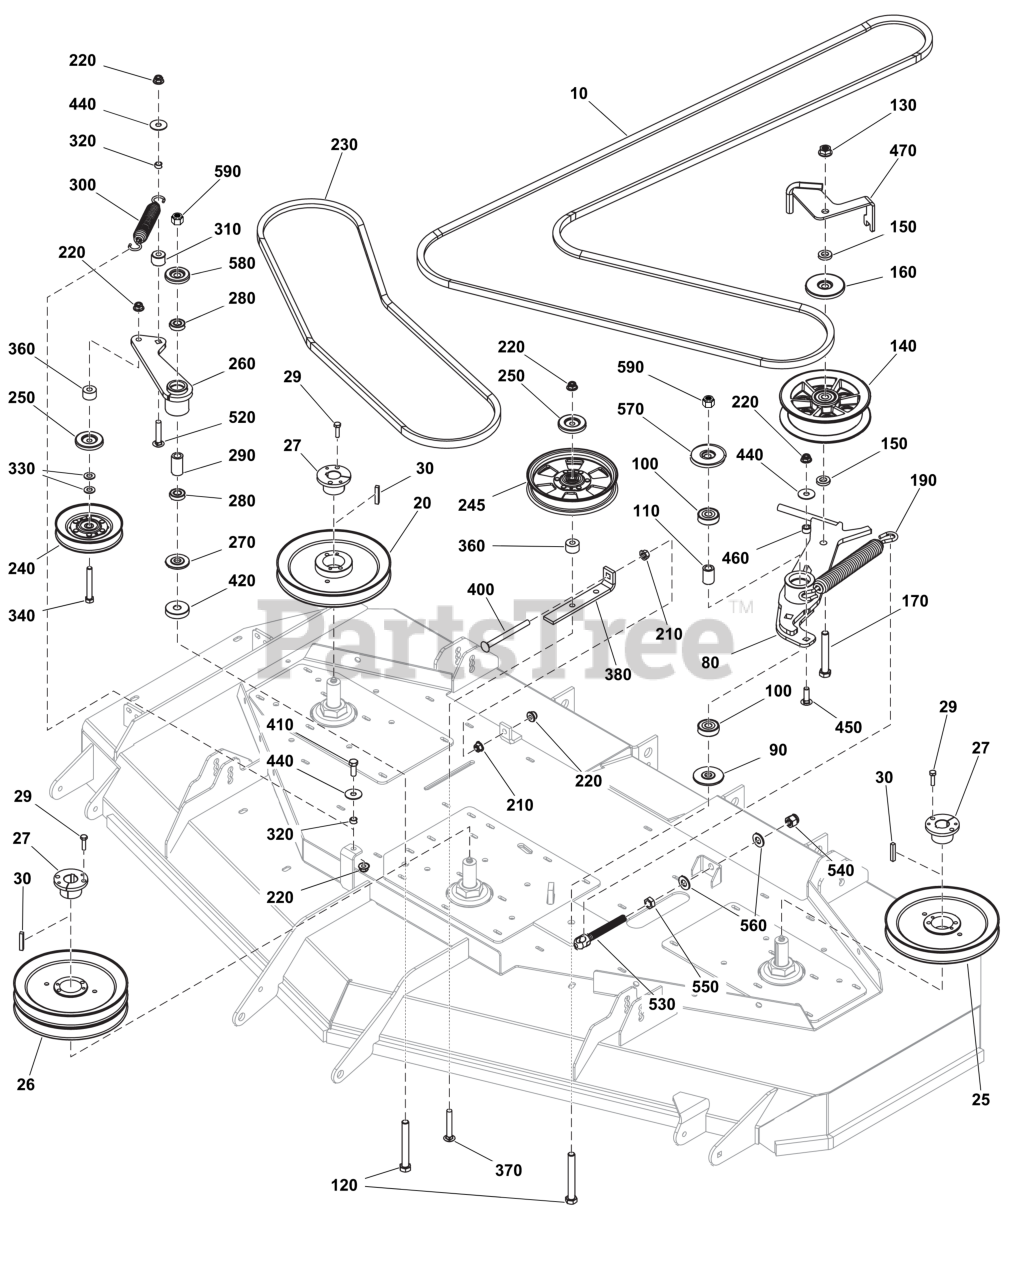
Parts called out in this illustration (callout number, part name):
10	BELT, 5V/SPB, 156.70 EL, LG ARAMID, WRPD
20	PULLEY, SPNDL, 8.37"OB, HQ BORE -RH
25	PULLEY, SPNDL, 8.37"OB, HQ BORE -LH
26	PULLEY, SPNDL, 8.37"OB-DBL, HQ BORE
27	BUSHING, Tapered Hub
29	BOLT, 1/4-20 X 1" GD5 CZ
30	KEY 1/4 SQ X 1 1/2 LONG
80	WELD, IDLER ARM, 2B DECK DRIVES - BLK
90	SPACER, IDLER ARM, 1/2 X 2.25
100	BEARING, 6203-1/2", SEALED
110	SPACER, .51 X .84 X 1.22, PM, CZ
120	BOLT, 1/2-13 X 4" GD5 CZ
130	NUT, Hex Flange, Nylock, 1/2-13
140	PULLEY, IDLER, 5.50, CI
150	SPACER, .52 X 1.00 X .22, PM, CZ
160	SHIELD, PULLEY, 1/2"ID X 2-7/8"OD, CZ
170	BOLT, 1/2-13 X 3-1/2, HEX HD, GD5, CZ (SV)
190	SPRING, EXT1.22"ODX10.5"FLX.192"WIRE BLK
210	NUT, 3/8-16 Hex Large Serrated Flange
220	NUT, 3/8 - 16 HEX NYLOCK FLANGE
230	BELT, B-SEC, 76.40 EL, ARAMID, WRPD
240	PULLEY, V-IDLER, 5"OD X 3/8", CZ, TE
245	PULLEY, FLT IDLR, 6.0 X 1.0 X .38, CZ
250	SHIELD, PULLEY, 3/8"ID X 2"OD, CZ
270	SPACER, IDLER ARM, 1/2, PM
280	BEARING, BALL, AXLE
290	SPACER, .52 X .84 X 1.53, PM
300	SPRING-EXT, 1.04 ODX6.935LGX.148WR, BLK
310	SPACER, .39 X 1.00 X .75, CZ
320	SPACER, .38 X .50 X .27, CZ
330	WASHER, 3/8 SAE
340	BOLT, 3/8-16 X 2-3/4" GD5 CZ
360	SPACER, .39 X 1.00 X .63, CZ
370	BOLT, 3/8-16 X 2-1/2, CARRIAGE, GD5, CZ
380	PLATE, IDLER PUSHER, 72 - BLK
400	BOLT, 3/8-16 X 4-1/2, CARRIAGE, GD5, CZ
410	BOLT, 3/8-16 X 1" GD5 CZ
420	SPACER, .52 X 1.75 X .420, CZ
440	WASHER, 3/8" Fender
450	BOLT,3/8-16X1-1/4,GR5,CARRIAGE,ZC/CL
460	SPACER, .39 X .63 X .375M DOM CZ
470	WELD, UPPER ARM GUIDE - BLK
520	BOLT, 3/8-16 X 2, CARRIAGE, GD5, CZ
530	SPRING PULLER, 1/2-20, 5.00
540	NUT, Hex, Nylon Lock, 1/2-20
550	NUT, 1/2-20 Hex Jam
560	WASHER, 1/2 SAE
570	SHIELD, BEARING, 1/2" ID-2.5"
580	SHIELD, BEARING, 1/2" ID-1.75"
590	NUT, 1/2-13 HEX NYLON LOCK
